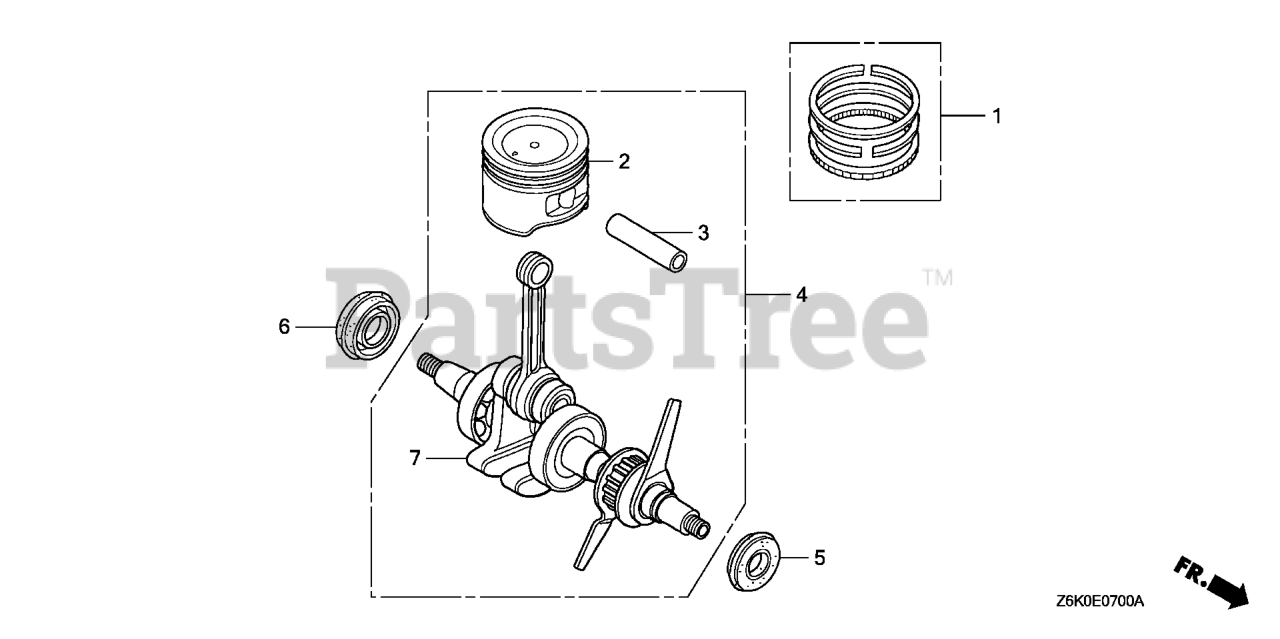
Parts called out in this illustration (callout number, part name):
1	RING SET, PISTON (RIKEN)
1	RING SET, PISTON (TPR)
2	PISTON
3	PIN, PISTON
4	CRANKSHAFT
5	OIL SEAL (10X20X5)
6	OIL SEAL (15X25X6)
7	CRANKSHAFT
